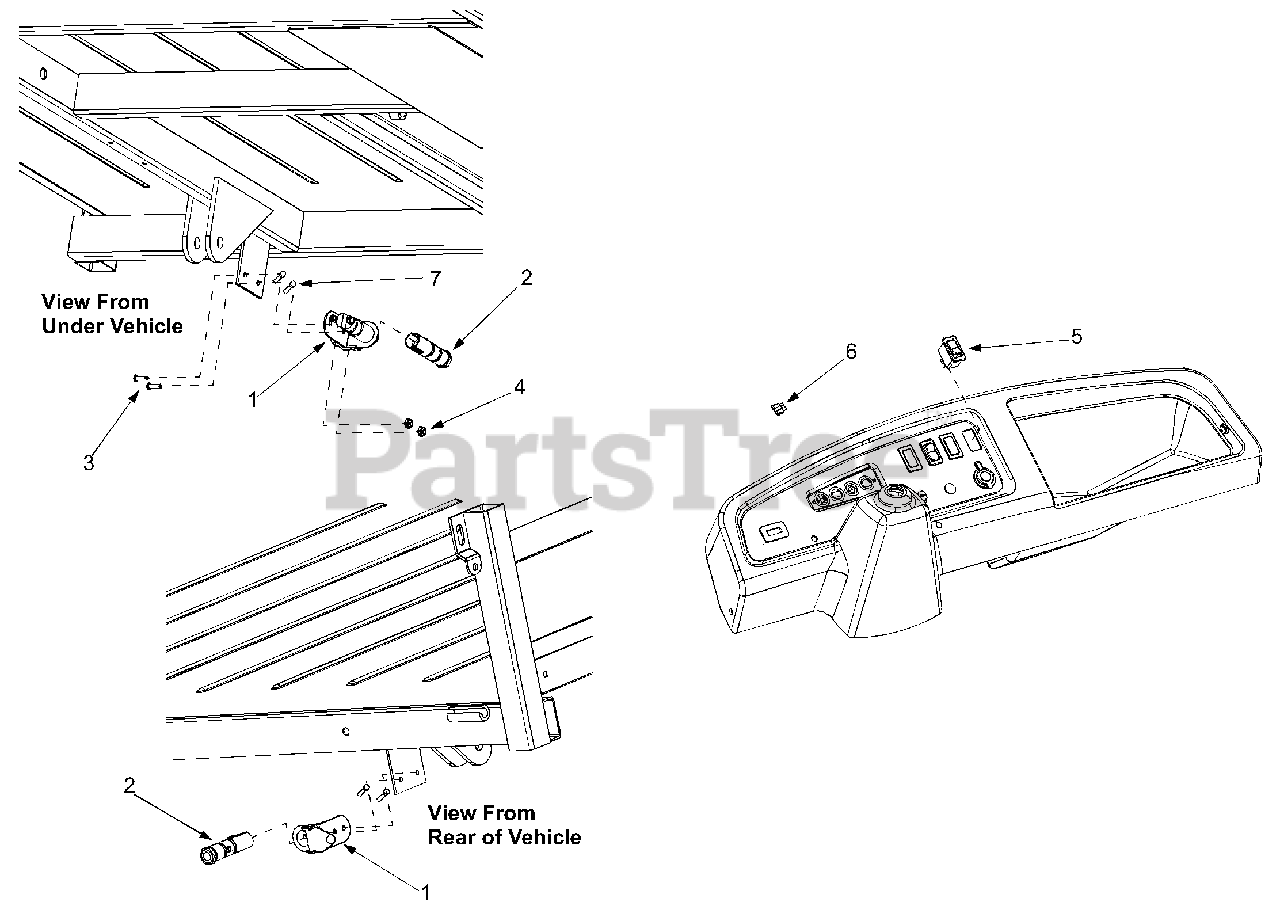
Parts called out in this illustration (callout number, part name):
1	Power Reciprocal
2	Plug Reciprocal
3	Machine Screw 10-32 x .50
4	Hex Lock Nut #10-32
5	Power Switch
6	Fuse 15 amp
7	Terminal Ring, #10, 16-14G
